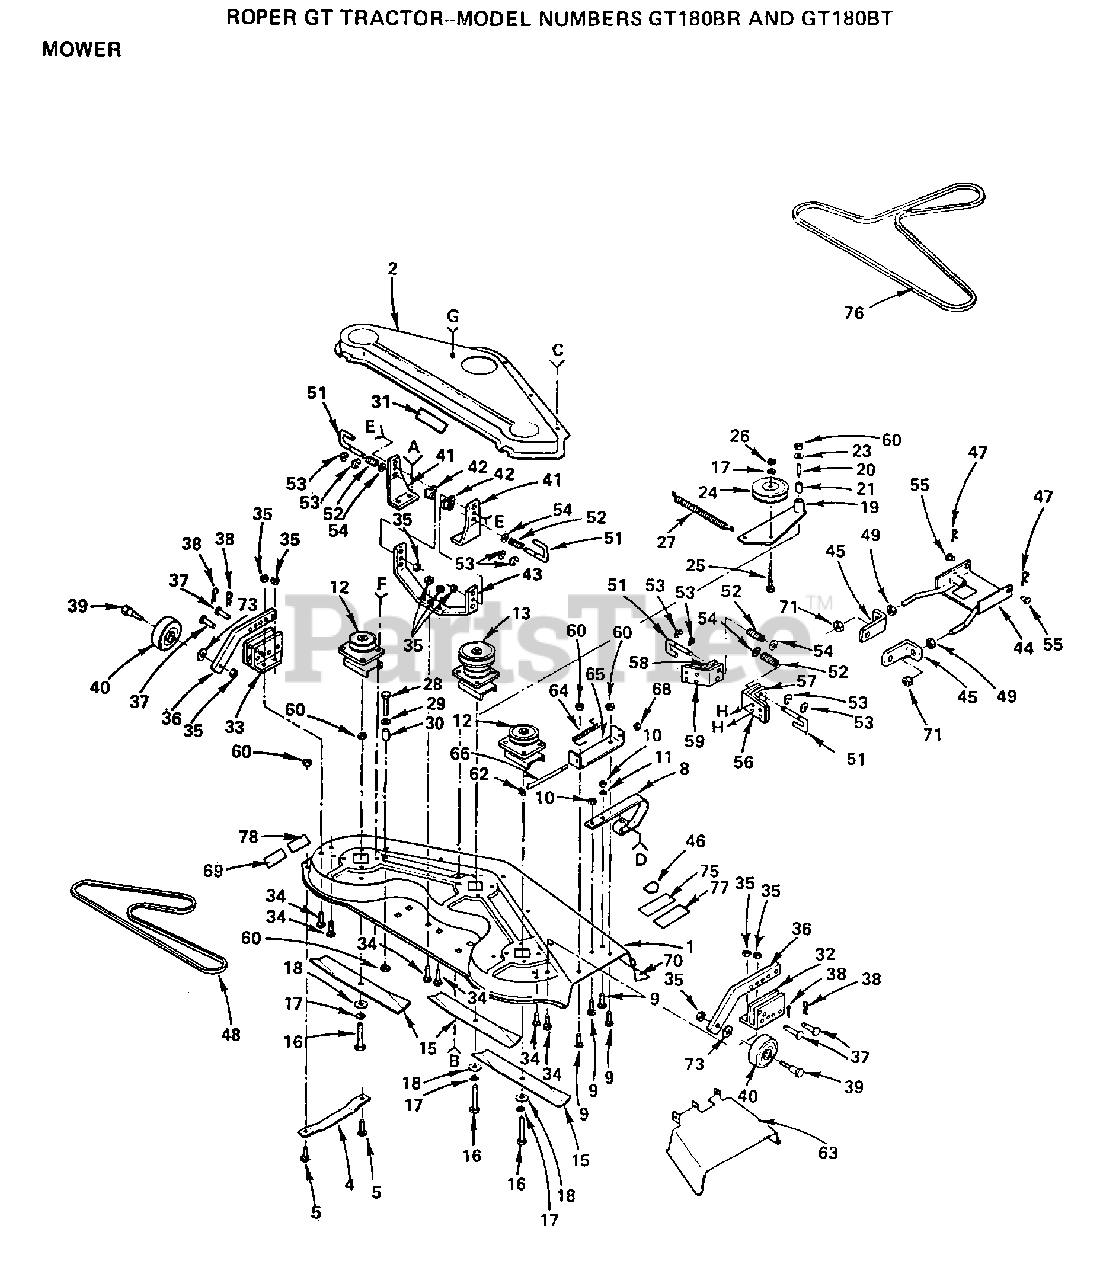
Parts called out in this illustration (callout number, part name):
2	DECK DRV COVE T
4	RUNNER-LH M
5	BOLT
9	BOLT
11	WASHER
16	BOLT.3/8-24X1-1/2
17	LOCKWASHER
18	WASHER
19	ARM ASSY GT
23	WASHER
24	IDLER-FLAT T
26	NUT.HEX.3/8-16UNC
27	SPRING T
28	BOLT
29	WASHER M
30	SPACER SPLIT LT
32	GUAGE WHL BRKT GT
33	GUAGE WHL BRKT GT
34	BOLT
36	GUAGE WHL BAR GT
39	BOLT M
40	WHEEL.GAGE.BLK.PL
41	SUSP BRKT GT
43	SUSP BRACE GT
44	SUSP PLATE GT
45	SUSP BRKT GT
46	DECAL HYT
47	RETAINER.SPRING
48	V-BELT
49	NUT LTV
51	RELEASE PIN GT
52	SPRING M
53	KLIP RING
55	CLEVIS PIN GT
56	OUTER BRKT RH GT
57	INNER BRKT RH GT
58	INNER BRKT LH GT
59	OUTER BRKT LH GT
62	WASHER
66	ROD-HINGE T
69	DECAL INSTRUCTION CAUTION
70	DECAL - SAFETY STANDARD
71	NUT
73	WASHER
75	DECAL.WARNING.T
78	DECAL-INST YT
